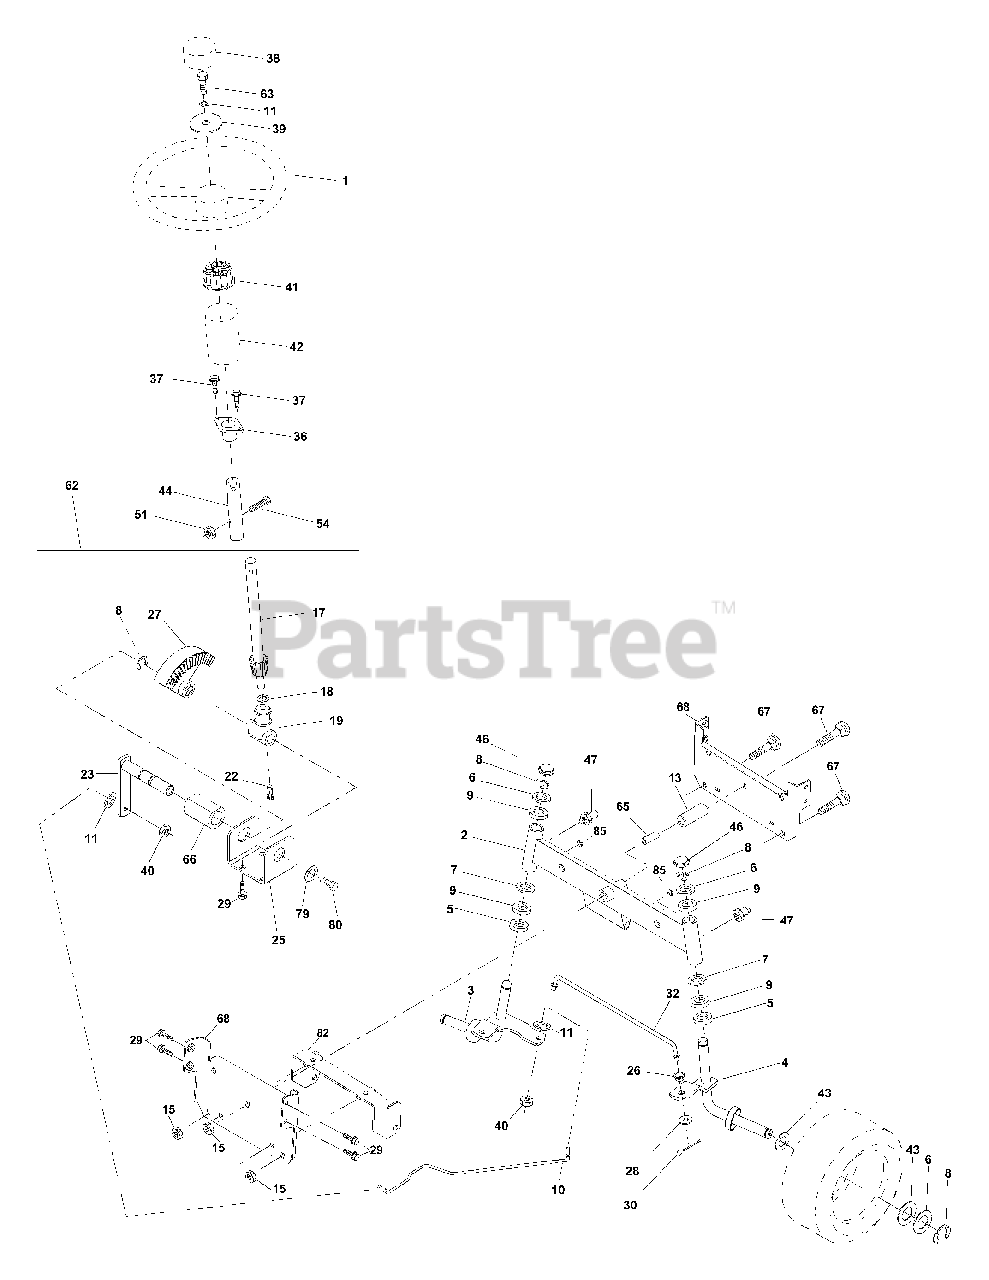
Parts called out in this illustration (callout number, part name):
1	Wheel Steering Ayp/P/L Blk
2	Axle Asm
3	Spindle Asm LH
4	Spindle Asm RH
5	Bearing Race Thrust Harden
6	Washer 25/32 X 1-5/8 X 16 Ga
7	Washer 27/32 X 1-1/4 X 16 Ga
8	Ring Klip #t5304-75
9	Bearing Col Strg Blk
10	Link Drag
11	Washer Lock Hvy Hlcl Spr 3/8
13	Spacer earing Axle Front
15	Hexflange Lock
17	Shaft Asm Strg
18	Washer Thrust 515x 750x 033
19	Support Shaft
22	Screw Hex Wsh Hd Torx
23	Shaft Asm Pittman
25	Bracket Steering
26	Bushing Link Drag Blk LR
27	Gear Sector
28	Washer 13/32 X 7/8 X 16 Ga
29	Screw 3/8-16 x 3/4
30	Pin Cotter 1/8 X 3/4 Cad
32	Rod Tie Wire Form 19 75 Mech
36	Bushing Strg 5/8 Id Dash
37	Screw
38	Cap Wheel Steer Ayp
39	Washer 13/32 x 2-3/8 x 12 Ga.
40	Nut Lock Center 3/8-24un
41	Adaptor Wheel Strg
42	Boot Dash Mtl Steering Blk
43	Washer 25/32 X 1 1/4 X 16 Ga
44	Extension Steering
46	Cap Spindle Fr Top Blk
47	Fitting Grease
51	Nut Lock Hex W/Ins 5/16-18
54	Bolt Fin Hex 3/8-16unc x 1-1/4
62	Kit Steering Assembly Service
63	Bolt Fin Hex 3/8-16unc x 1 Gr.5
65	Spacer Brace Axle
66	Bearing Arm Pittman
67	Bolt Fin Hex 5/8-11 unc x 2-3/4
68	Brace Axle
79	Washer 13/32 x 1 1/4 x 12 Ga.
80	Bolt Hex 3/8-16 x 3/4
82	Bracket Susp Chassis Front
85	Fastener Christmas Tree
